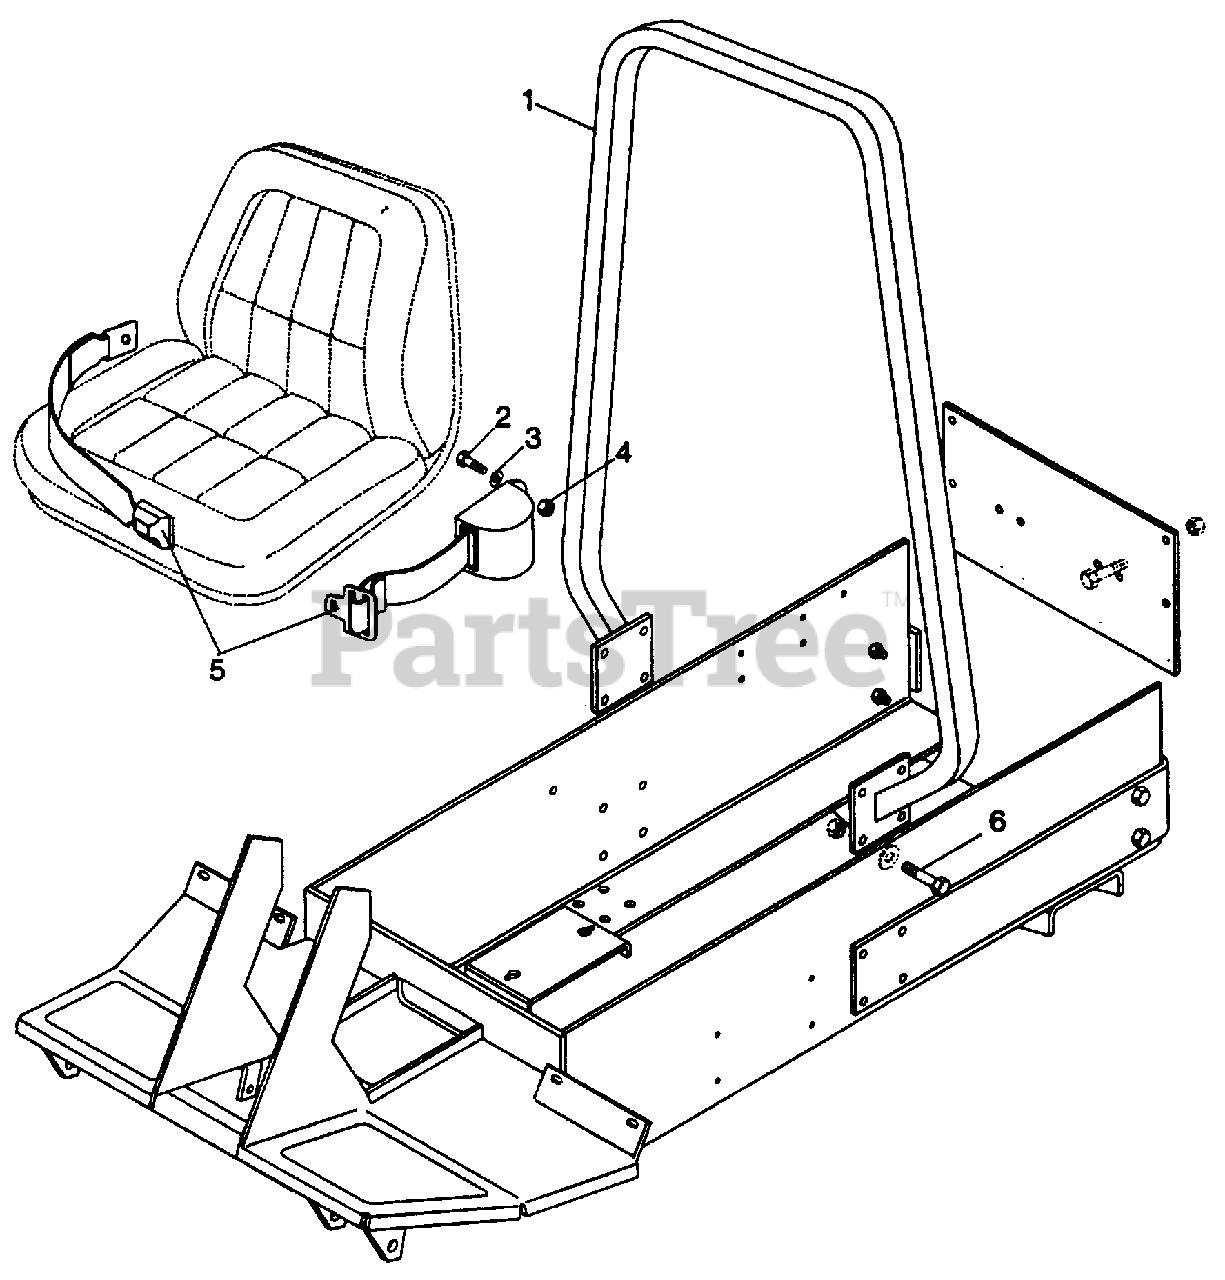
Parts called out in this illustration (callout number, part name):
1	WELDMENT, ROLLOVER BAR
2	BOLT, HEX 7/16-14X1.00
3	WASHER, FLAT .531X1.062X.095
4	NUT, LOCK 7/16-14
5	ASSEMBLY, SEAT BELT
6	BLT-HEX .50-13 X 1.75 PL GR 8
